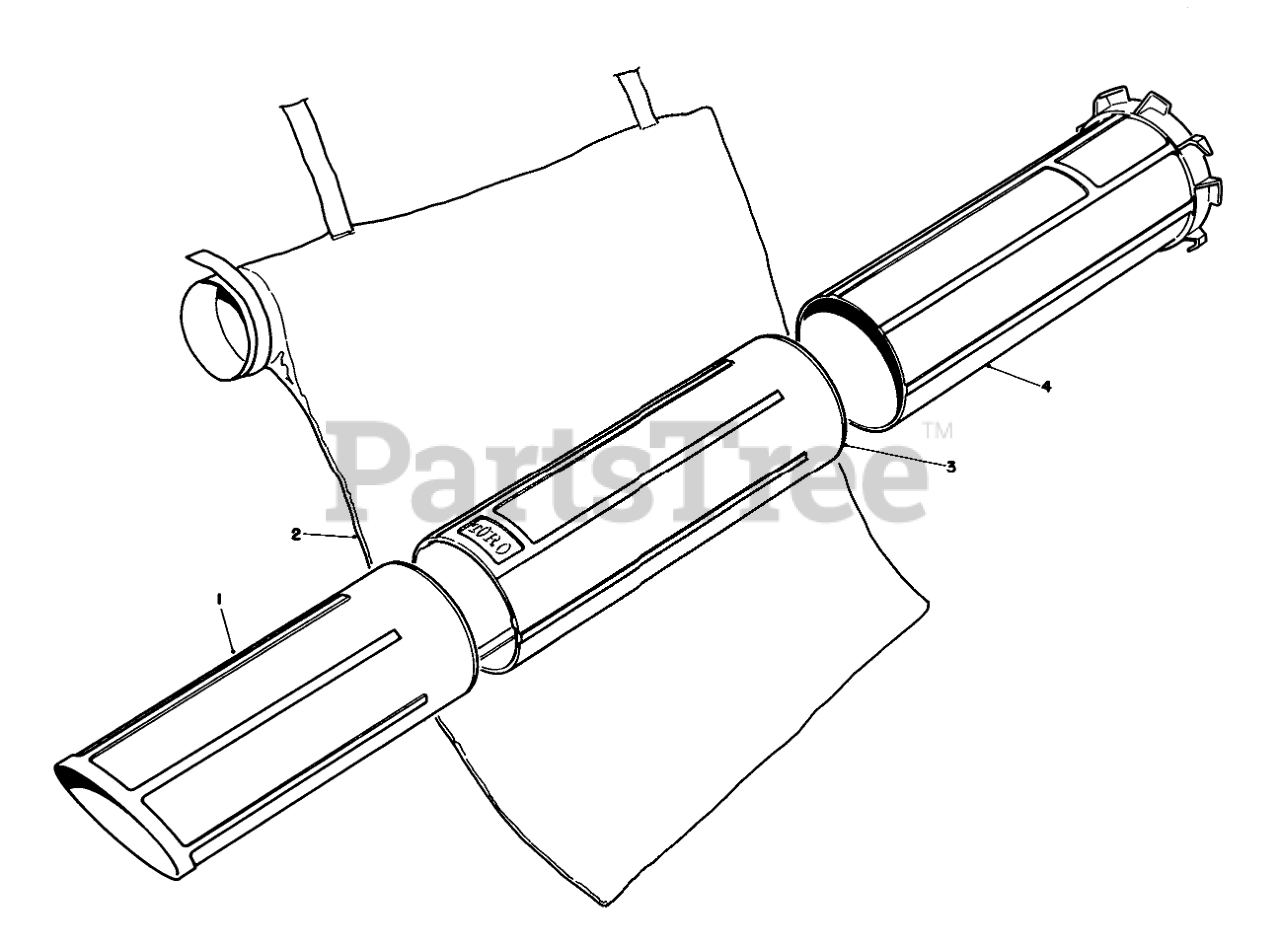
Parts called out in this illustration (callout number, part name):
1	VACUUM BAG
2	Tube-Vacuum, Upper
3	LOWER VAC TUBE
4	MIDDLE VAC TUBE
